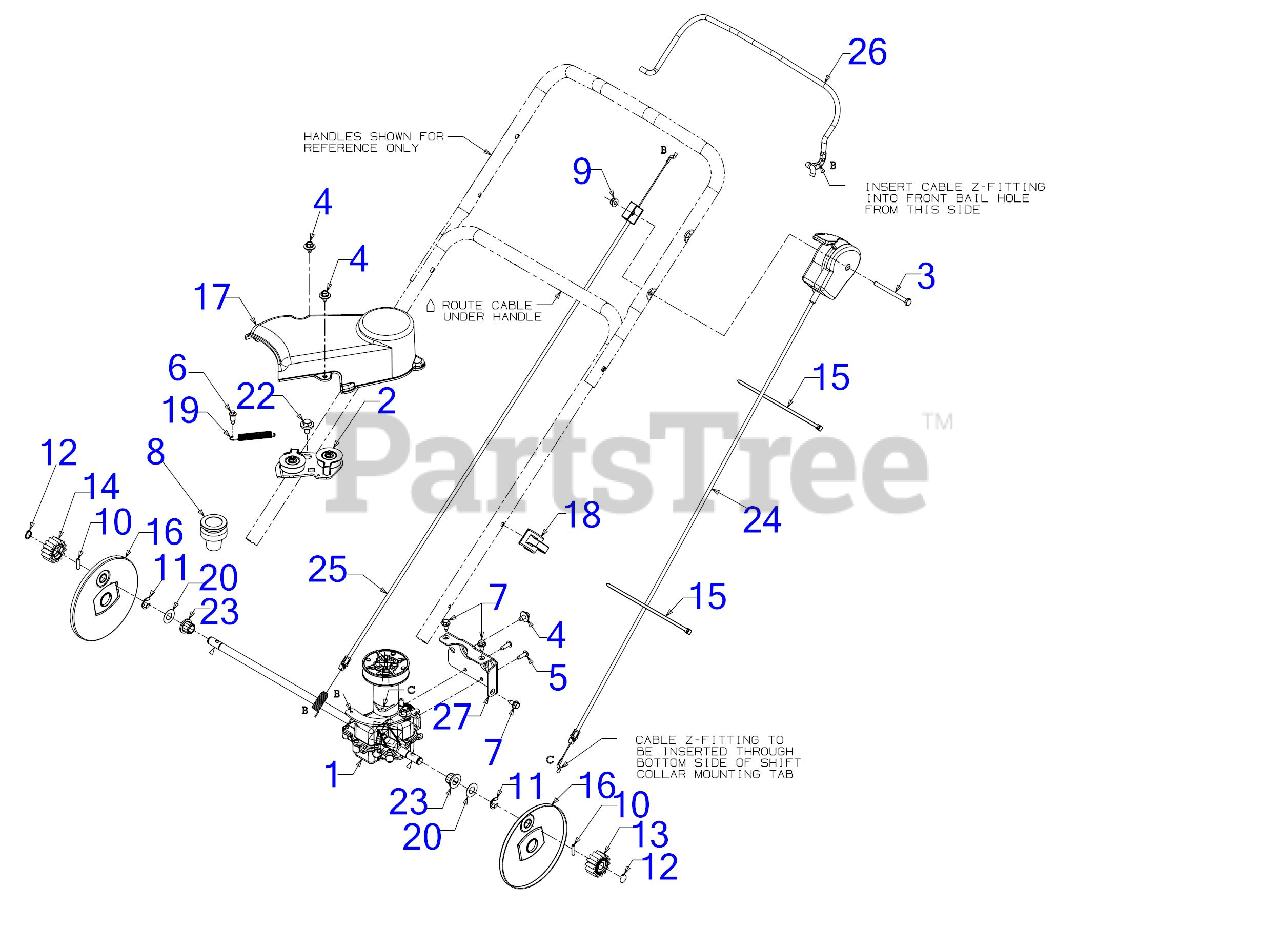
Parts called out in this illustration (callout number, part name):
1	TRANSMISSION ASSEMBLY
2	IDLER ASSEMBLY (COMPONENTS)
3	SCREW 1/4-20 x 3.0 GR5
4	SCREW 1/4-20 x .50
5	SCREW #12-16 x .750
6	SCREW .30 x .46
7	SCREW 1/4-20X.625
8	IMPELLER INSERT HUB
9	FLANGE LOCK NUT
10	DOWEL PIN
11	E-RING FOR .500
12	SNAP RING FOR .500
13	SPUR GEAR 14T (LH)
14	SPUR GEAR 14T (RH)
15	7" CABLE TIE
16	DUST WHEEL COVER
17	BELT COVER
18	CABLE GUIDE
19	EXTENSION SPRING
20	FLAT WASHER
22	SHOULDER SCREW .560X.165: 5/16-18
23	HEX FLANGE BEARING .506ID x .590LG
24	SPEED CONTROL CABLE
25	CONTROL CABLE
26	GULLWING DRIVE BAIL- RED
27	MOUNTING BRACKET
